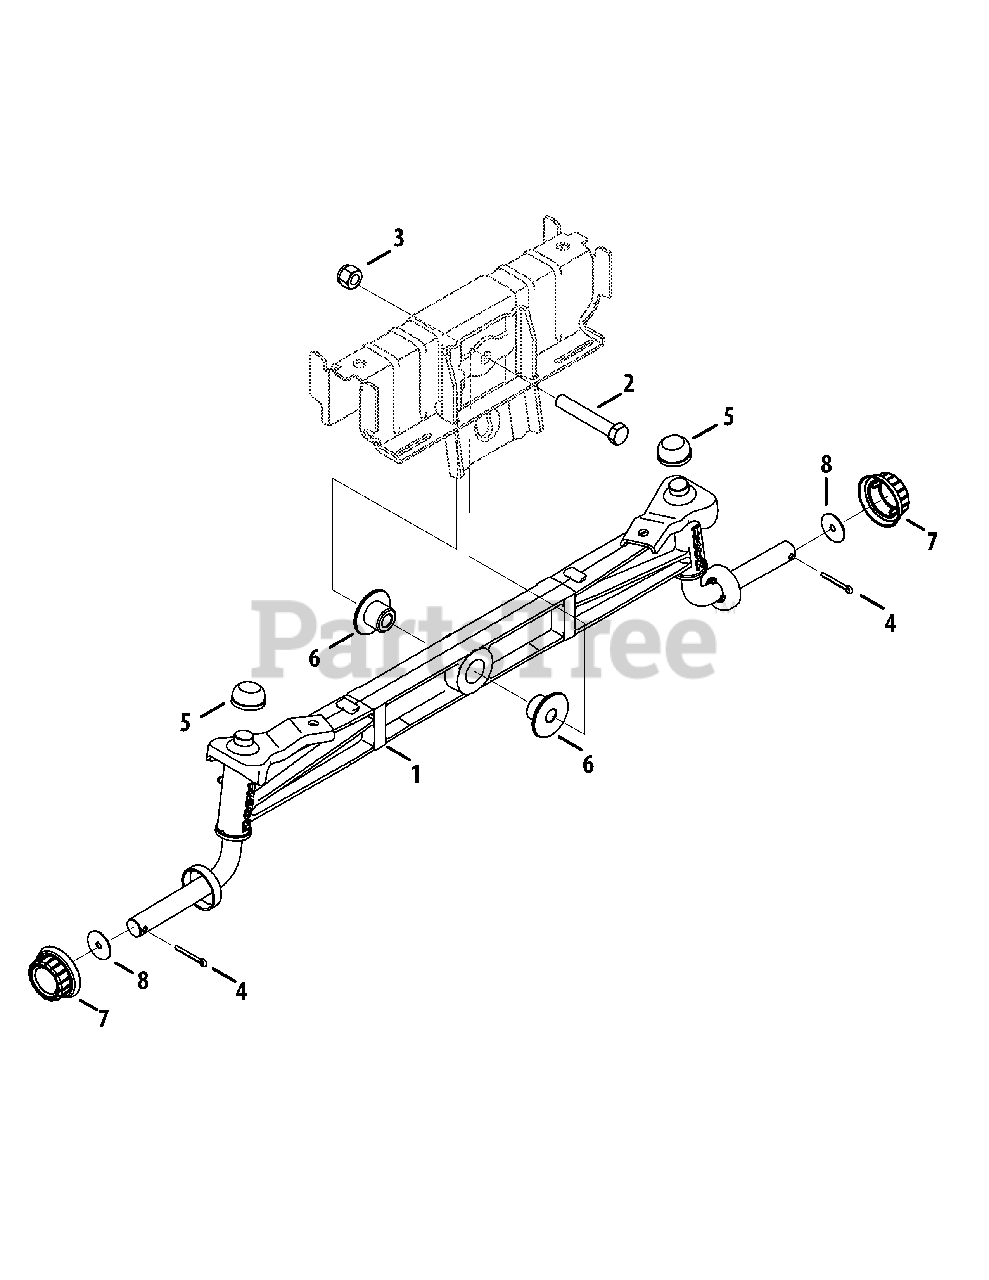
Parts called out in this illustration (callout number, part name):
1	Front Pivot Axle Assembly
2	Hex Cap Screw, 1/2-13 x 3.00
3	Nut, Hex Lock, 1/2-13
4	Pin, Cotter, 5/32, 1.25
5	Push Cap, 3/4
6	Shoulder Spacer, 1.00 x .515 x .760
8	Flat Washer, .755 x 1.92 x .060
